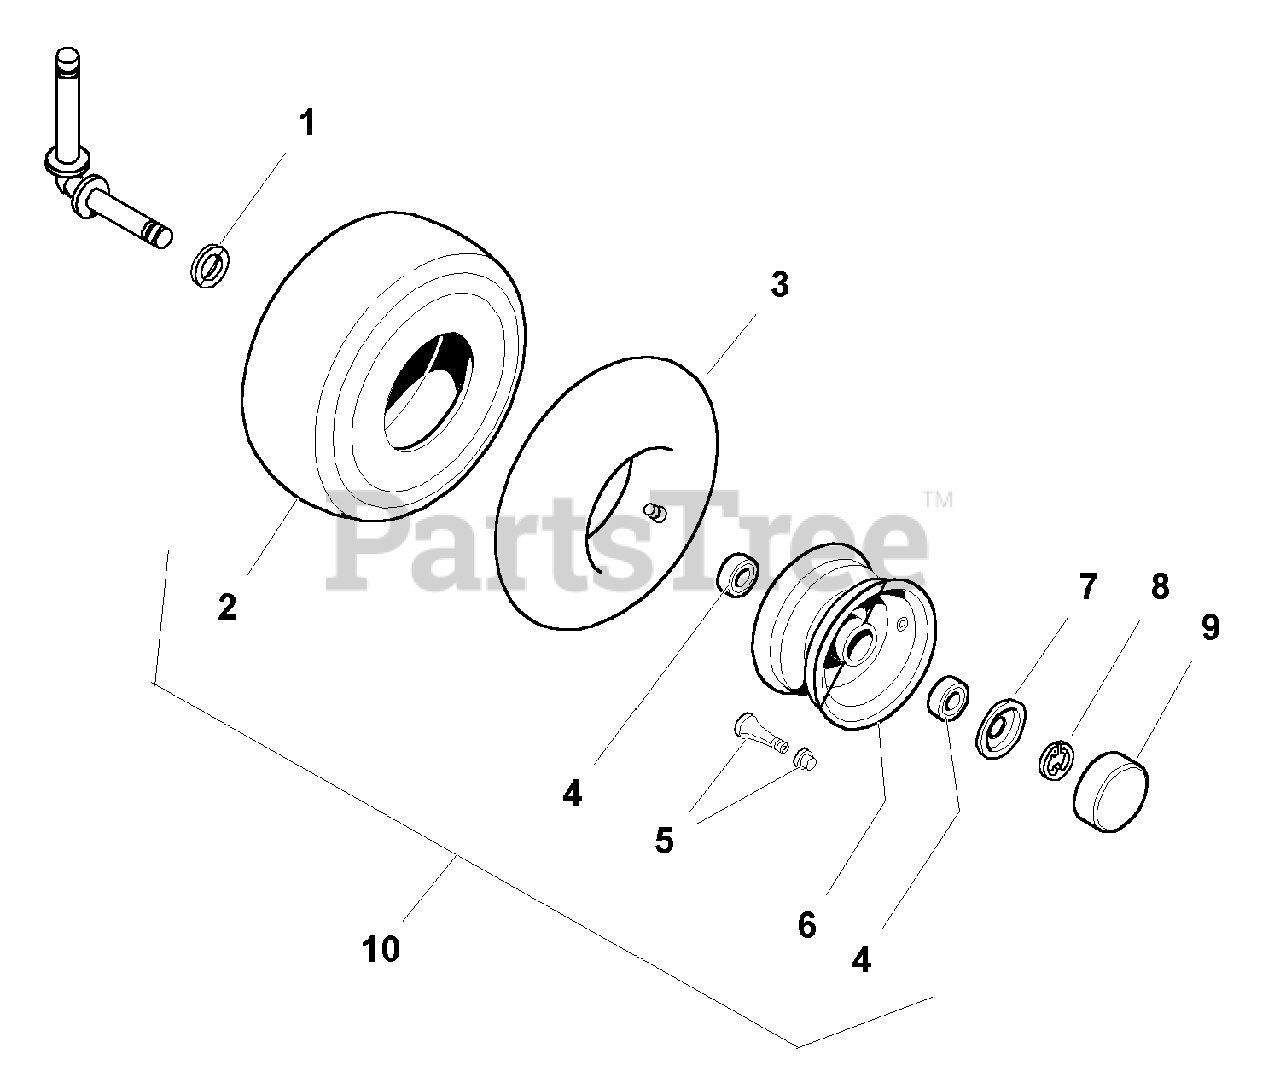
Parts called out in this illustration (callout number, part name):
1	WASHER, Special 3/4 (Install to the inside of wheel)
2	TIRE, 15 x 6.00-6 (Dico), Mulit Trac
3	TUBE, 4.10/3.50-6
4	BALL BEARING
5	VALVE STEM & CAP
6	WHEEL ASSEMBLY, Metallic Gray (Includes Ref. No. 4)
7	RETAINER, Cap, Hub
8	RING, Retaining
9	CAP, Hub, Black Poly
10	WHEEL & TIRE ASSEMBLY 15 x 6.00-6, Metallic Gray (Includes Ref. Nos. 2, 4, 5, & 6)
